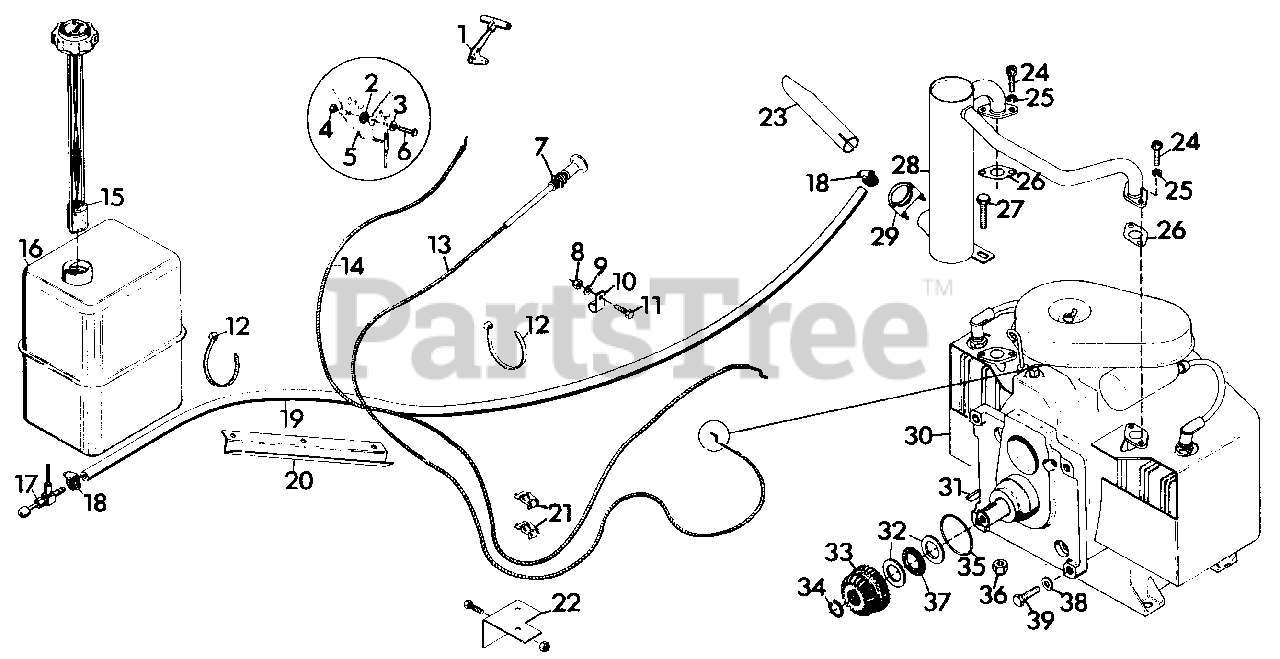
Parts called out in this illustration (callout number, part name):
1	ASSEMBLY, KNOB AND LEVER
2	WASHER, FRICTION
3	WASHER, SPRING
4	NUT, LOCK 1/4-28
5	BRACKET, MOUNTING
6	BOLT, HEX 1/4-20X.75
7	NUT, JAM 3/8-24 HEX
8	NUT, LOCK 5/16-18
9	WASHER, FLAT .343X.688X.065
10	CLAMP, NYLON
11	BOLT, HEX 5/16-18X1.00
12	TIE, CABLE
13	CONTROL, CHOKE
14	ASSEMBLY, CHOKE CONDUIT
15	GAUGE, GAS
16	TANK, FUEL
17	VALVE, FUEL 90 DEG. REVERSE FLOW
18	CLAMP, HOSE
19	LINE, FUEL
20	SHIELD, HEAT
21	CLIP, SPEED
22	BRACKET, THROTTLE AND CHOKE
23	EXTENSION, PIPE
24	SCREW, CAP 5/16-18X.75 SOCKET HD
25	WASHER, LOCK 5/16 REG.
26	GASKET, EXHAUST
27	BOLT, HEX 3/8-16X1.25
28	MUFFLER, EXHAUST
29	CLAMP, MUFFLER
30	ENGINE, 17-HP ELECTRIC 4-WHEEL
30	ENGINE, 19-HP ELECTRIC 4-WHEEL
31	KEY, SQUARE .250X1.250
32	RACE, BEARING THRUST 1.125X1.750X.123/.126
33	GEAR, SPUR AND BEVEL, INPUT
34	RING, RETAINING 1.125 SHAFT
35	O-RING, 3.000X3.188X.094
36	NUT, LOCK 3/8-16
37	BEARING, THRUST 1.127X1.740X.078
38	WASHER, LOCK 1/2 REG.
39	BOLT, HEX 1/2-13X1.75
NS	NUT, LOCK 10-32
NS	SCREW, MACHINE 10-32X.50 PHD
